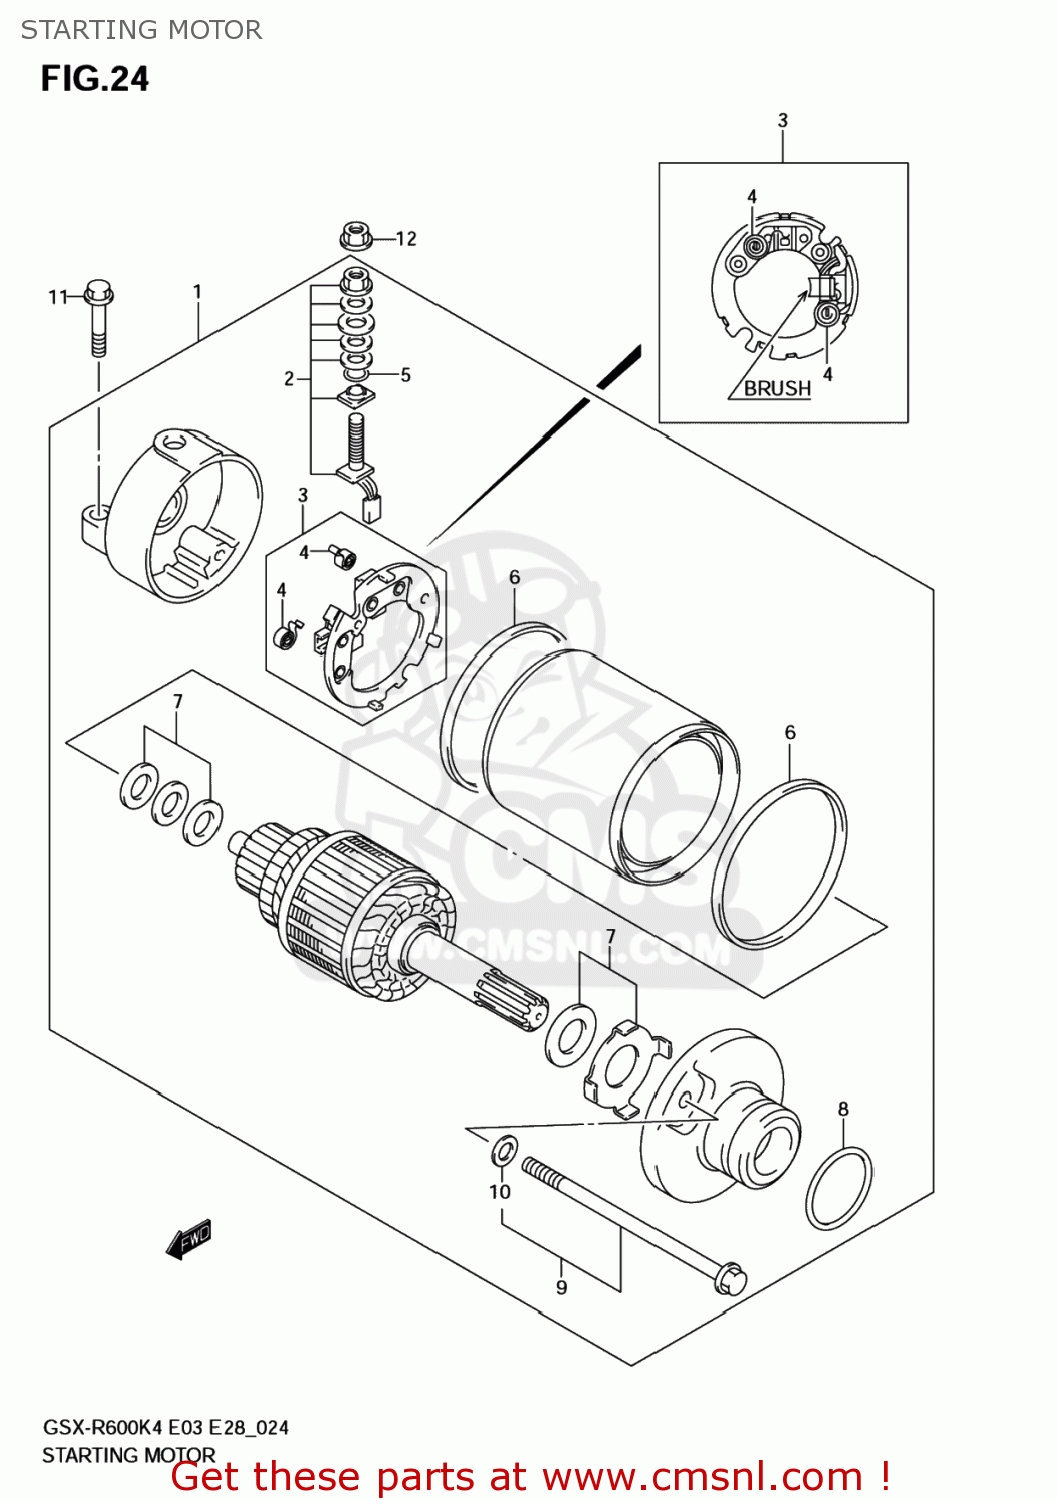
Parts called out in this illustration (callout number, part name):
1	MOTOR ASSEMBLY,STARTING
2	BRUSH TERMINAL SET
3	BRUSH HOLDER SET
4	SPRING,BRUSH
5	O RING
6	O RING
7	SHIM SET,STARTING MOTOR
8	O RING(D:3,ID:24.5)
9	BOLT
10	O RING
11	SCREW (6X25)
12	NUT
